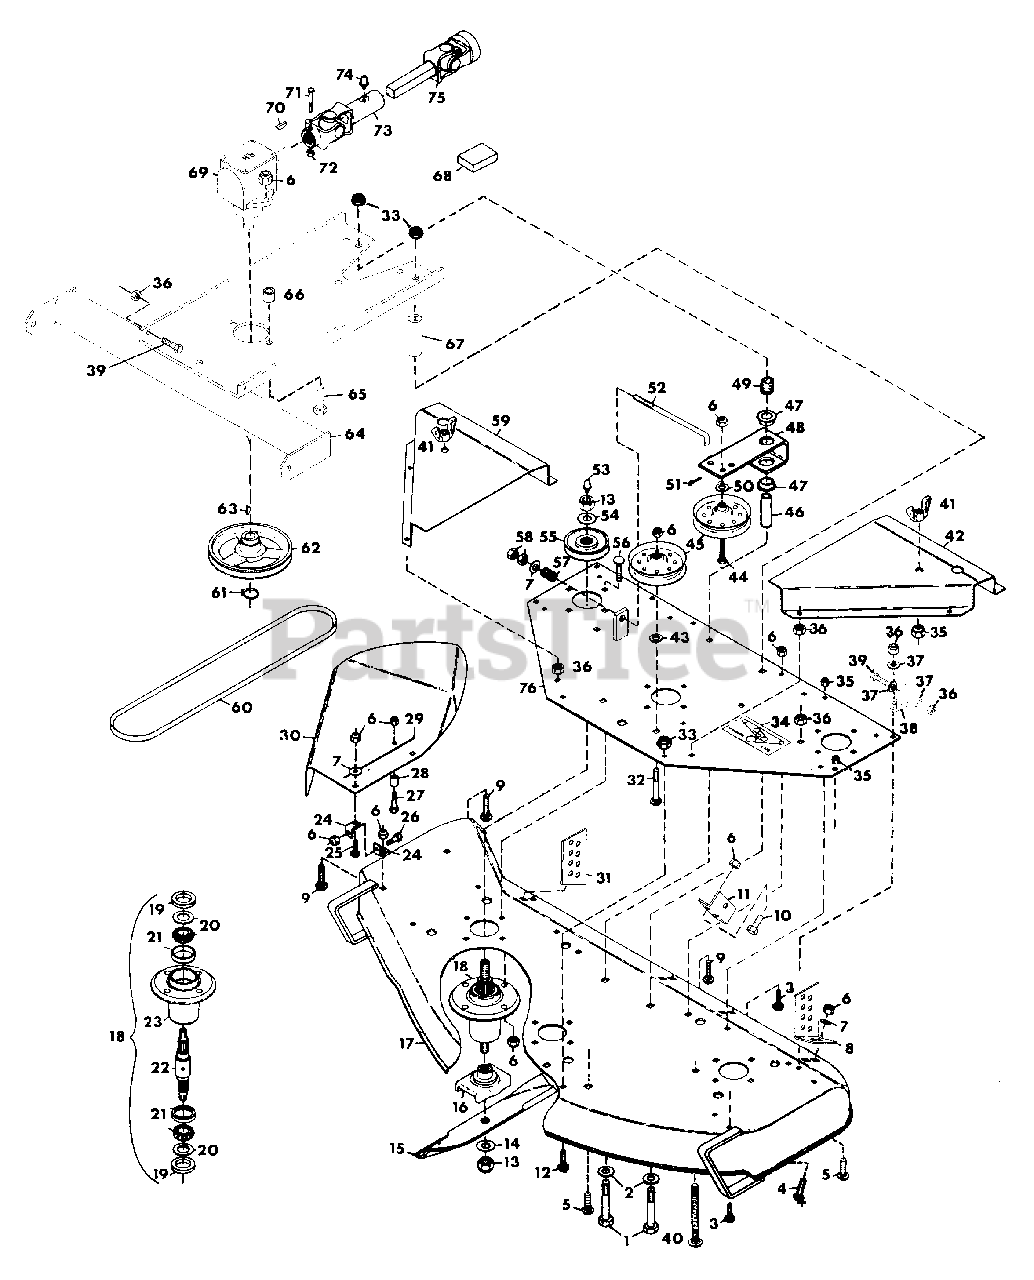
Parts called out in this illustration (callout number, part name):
1	BOLT, HEX 1/2-13X3.75
2	WASHER, FLAT .531X1.062X.095
3	BOLT, CARRIAGE 5/16-18X.75
4	BOLT, HEX 3/8-16X1.25
5	BOLT, CARRIAGE 5/16-18X1.00
6	NUT, LOCK 3/8-16
7	WASHER, FLAT .406X.812X.065
8	PLATE, REAR ADJUSTMENT
9	BOLT, CARRIAGE 3/8-16X.75
10	BOLT, HEX 3/8-16X1.00
11	BRACKET, LIFT
12	BOLT, HEX 1/2-13X1.25
13	NUT, LOCK 5/8-11
14	WASHER, FLAT .656X1.312X.095
15	BLADE
16	WELDMENT, BLADE CRADLE
17	WELDMENT, 50 INCH DECK
18	ASSEMBLY, SPINDLE
19	SEAL, STEEL
20	WASHER, FLAT .975X1.970X.030
21	ASSEMBLY, BEARING
22	SHAFT, SPINDLE
23	HOUSING, BEARING
24	TAB, SPRING
25	BOLT, 3/8-16X1.00 RD HD SQ NK
26	BOLT, HEX 3/8-16X.875
27	BOLT, HEX 3/8-16X1.50
28	STOP, CHUTE
29	STRIPE
30	SHIELD, SAFETY EXTENSION 50 INCH MOWER
31	PLATE, REAR ADJUSTMENT
32	BOLT, 3/8-16X1.75 RD HD SQ NK
33	NUT, LOCK 1/2-13
34	DECAL, BELT INSTALLATION
35	NUT, LOCK 5/16-18
36	NUT, JAM 5/16-18 HEX
37	WASHER, FLAT .344X.688X.065
38	BRACKET, LIFT PIVOT
39	BOLT, HEX 5/16-18X1.50
40	BOLT, HEX 5/16-18X3.50
41	WINGNUT 5/16-18 W/INSP
42	COVER, PULLEY L.H.
43	WASHER, FLAT .438X1.00X.0832
44	BOLT, HEX 3/8-16X2
45	SHEAVE, IDLER
46	SPACER
47	BUSHING, NYLON .760X1.00X.600
48	ARM, IDLER PIVOT
49	SPRING, COMP.
50	SPACER, IDLER .406X.750X.188
51	PIN, COTTER 3/32X1.00
52	ROD, IDLER
53	FITTING, LUBE 1/8(LEFT AND RIGHT SPINDLE)
53	FITTING, LUBE .125 EXT.(CENTER SPINDLE)
54	WASHER, FLAT .687X1.312X.122/.146
55	SHEAVE, SPINDLE
56	BOLT, 3/8-16X1.25 RD HD SQ NK
57	SPRING, COMP. TYPE 1X.78X338 LB/IN
58	NUT, HEX 3/8-24
59	COVER, PULLEY R.H.
60	BELT, V .500X.312X126.3
61	RING, RETAINING .875 SHAFT
62	SHEAVE, DRIVE
63	KEY, WOODRUFF .250X.875 HARD #A
64	WELDMENT, PLATE SUPPORT
65	BOLT, HEX 3/8-16X2.25
66	SPACER, .375X.100X1.00
67	SPACER, .510X.840X2.43
68	KIT, REPAIR UNIVERSAL JOINT ROCKWELL STD.
68	KIT, REPAIR UNIVERSAL JOINT NEAPCO 1605X
69	GEARBOX, PRO MASTER-50
70	KEY, WOODRUFF .187X.75 HARD #9
71	BOLT, HEX 1/4-20X2.00
72	NUT, LOCK 1/4-20
73	ASSEMBLY, U-JOINT
74	FITTING, LUBE 1/4-28
75	SHAFT, PROP. SQ. BAR
76	WELDMENT, SUPPORT PLATE
NS	ASM., PRO MASTER-50 DRIVE
NS	DECAL, DANGER HAND
NS	DECAL, DANGER FOOT
NS	DECAL, WARNING EYE
NS	DECAL, PRO MASTER-50
